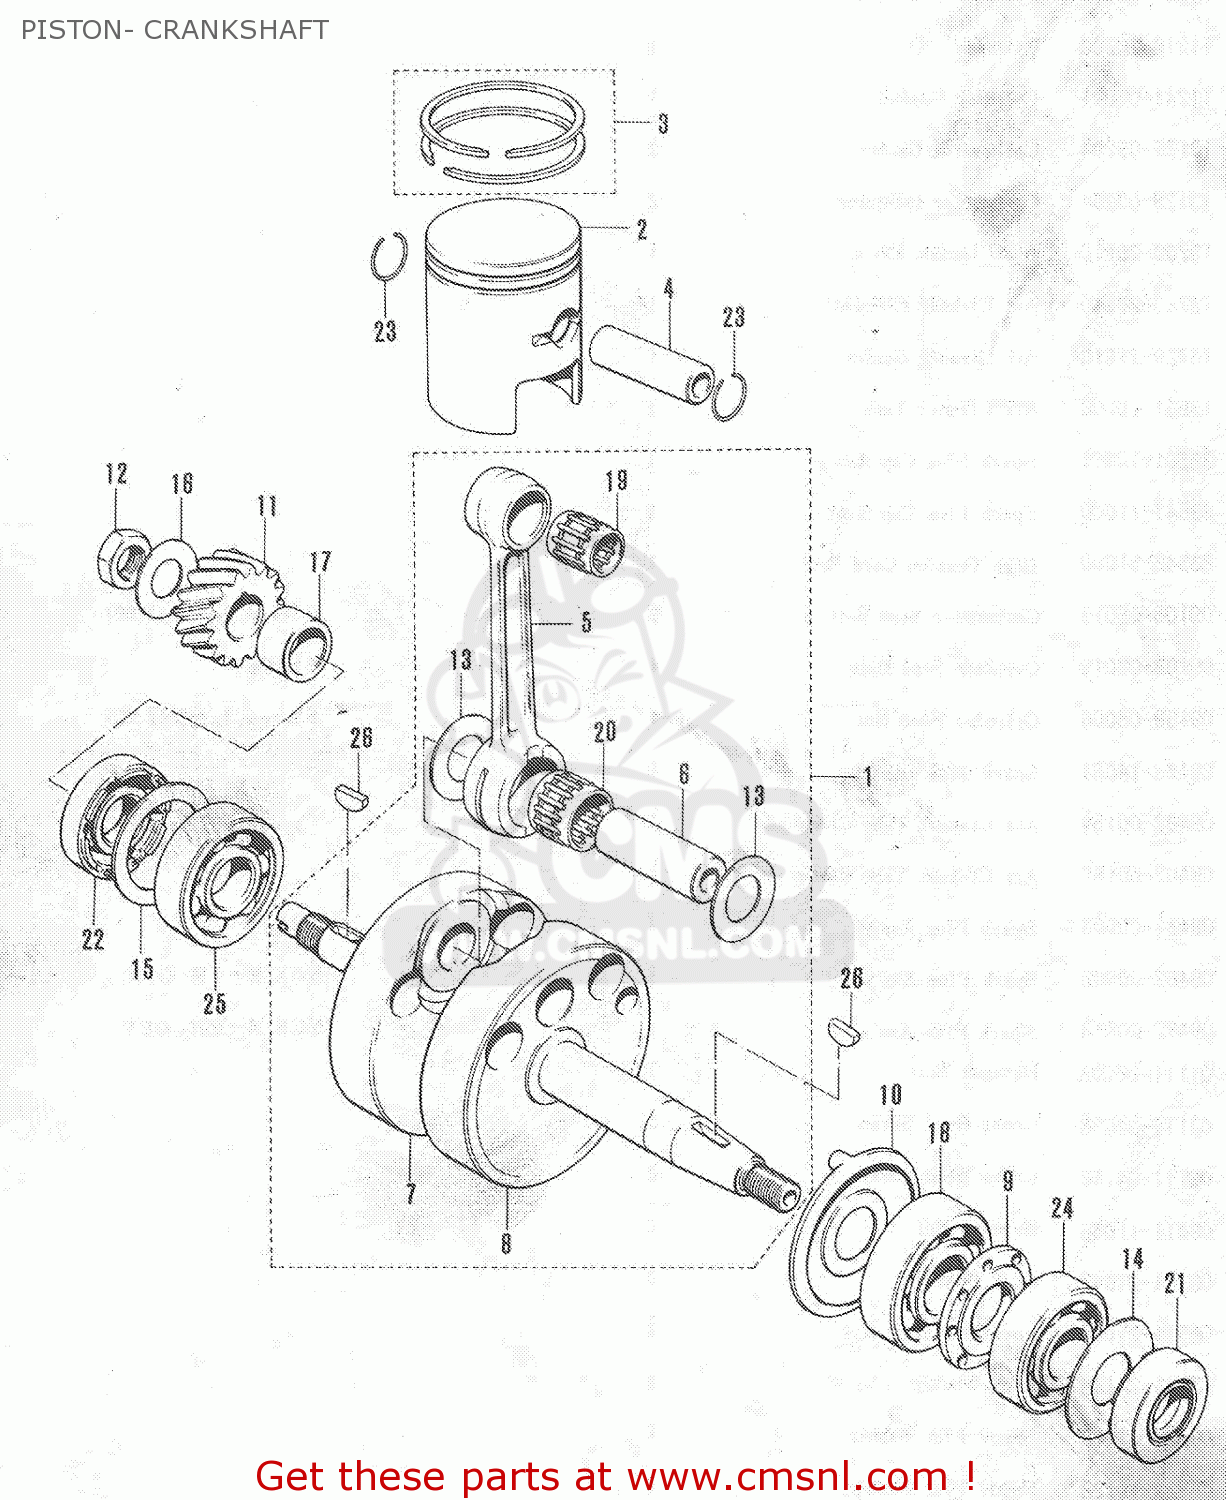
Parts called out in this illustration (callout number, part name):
1	CRANKSHAFT SET
2	PISTON
3	RING SET,PISTON
4	PIN,PISTON 14MM
5	CONNECTING ROD
6	PIN,CRANK
7	CRANKSHAFT
8	CRANKSHAFT,LEFT
9	SPACER
10	PLATE,CSHAFT OIL GUIDE
11	GEAR,PRIMARY DRIVE
12	NUT
13	WASHER (20X34X1)
14	WASHER(34X47X1)
15	WASHER(41X52X1)
16	WASHER
17	SPACER(20X26X14)
18	BEARING(20X52X15)
19	BEARING
20	BEARING
21	SEAL,OIL(20X40X9)
22	SEAL,OIL(26X47X9)
23	RING,SNAP 14MM
24	Bearing
25	BEARING
26	KEY 4MM
